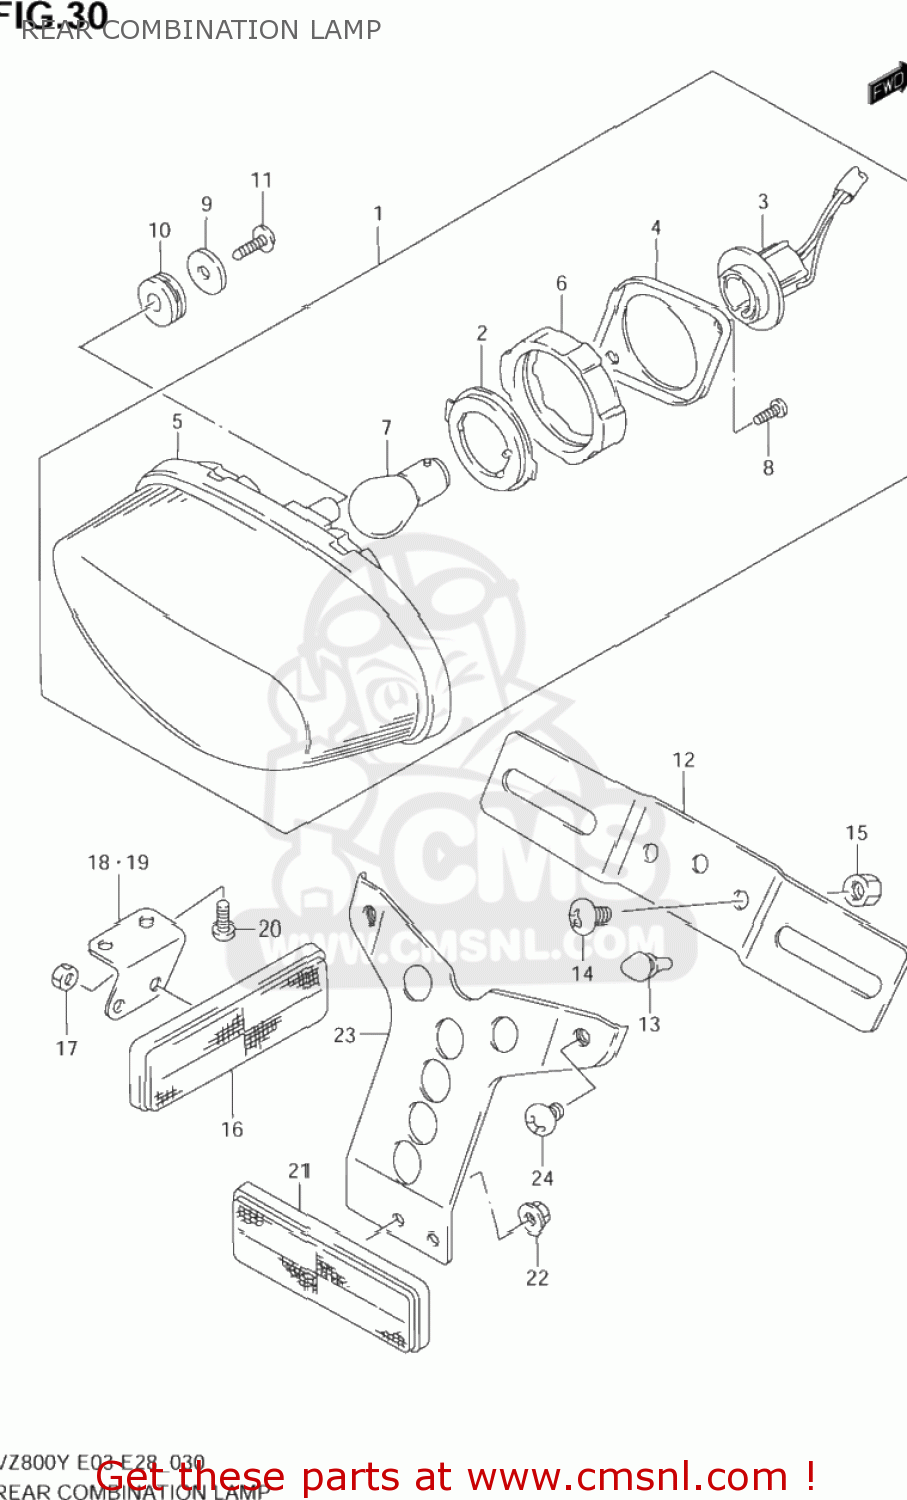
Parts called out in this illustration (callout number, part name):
1	LAMP ASSY,RR COMBINATION
2	PLATE NO.1
3	SOCKET & CORD
4	PLATE NO.2
5	LAMP UNIT
6	CUSHION
7	BULB(12V21/5W)
8	SCREW
9	WASHER(5.5X20X1.2)
10	CUSHION
11	SCREW
12	BRACKET,LICENSE PLATE
13	CUSHION
14	SCREW 6X12
15	NUT
16	REFLECTOR ASSY,RR
17	NUT
18	BRACKET,RR SIDE RR,L
19	BRACKET,RR SIDE RR,R
20	SCREW
21	REFLECTOR ASSY,RR
22	NUT
23	BRACKET,RR REFLECTOR
24	SCREW 6X12
